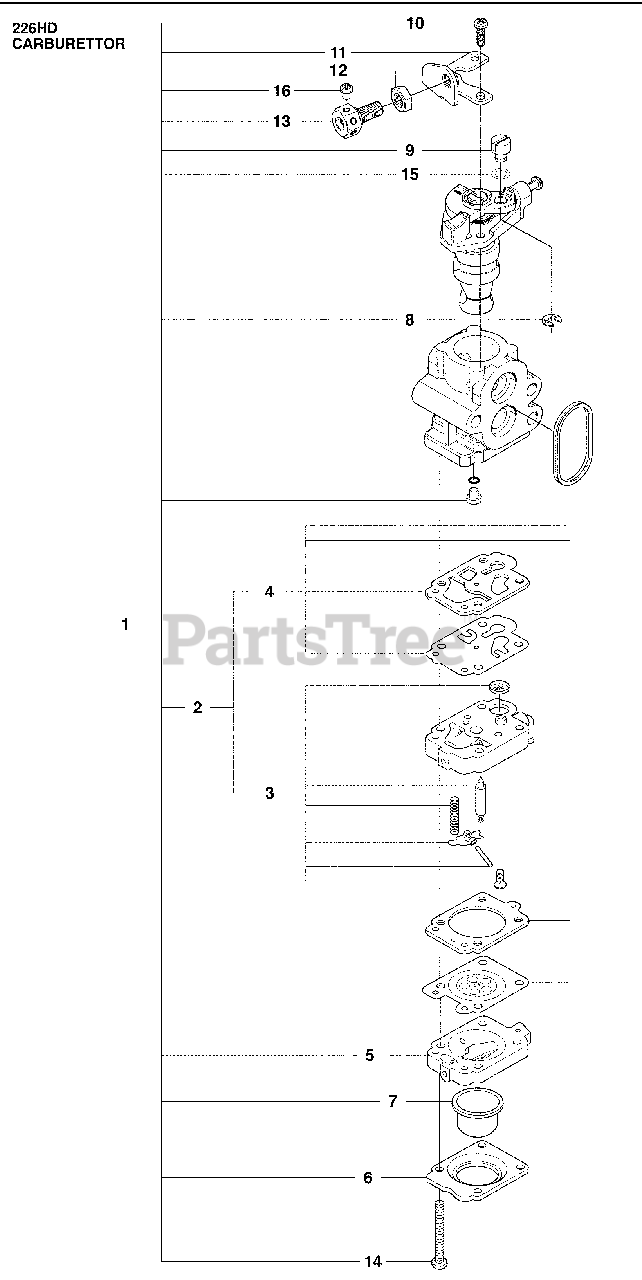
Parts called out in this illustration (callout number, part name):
1	Carburetor Assembly
2	Carburetor Rebuild Kit
4	Gasket Kit
5	Body
7	Primer Blub
12	Nut
13	Cable Adjust Screw
16	Screw
